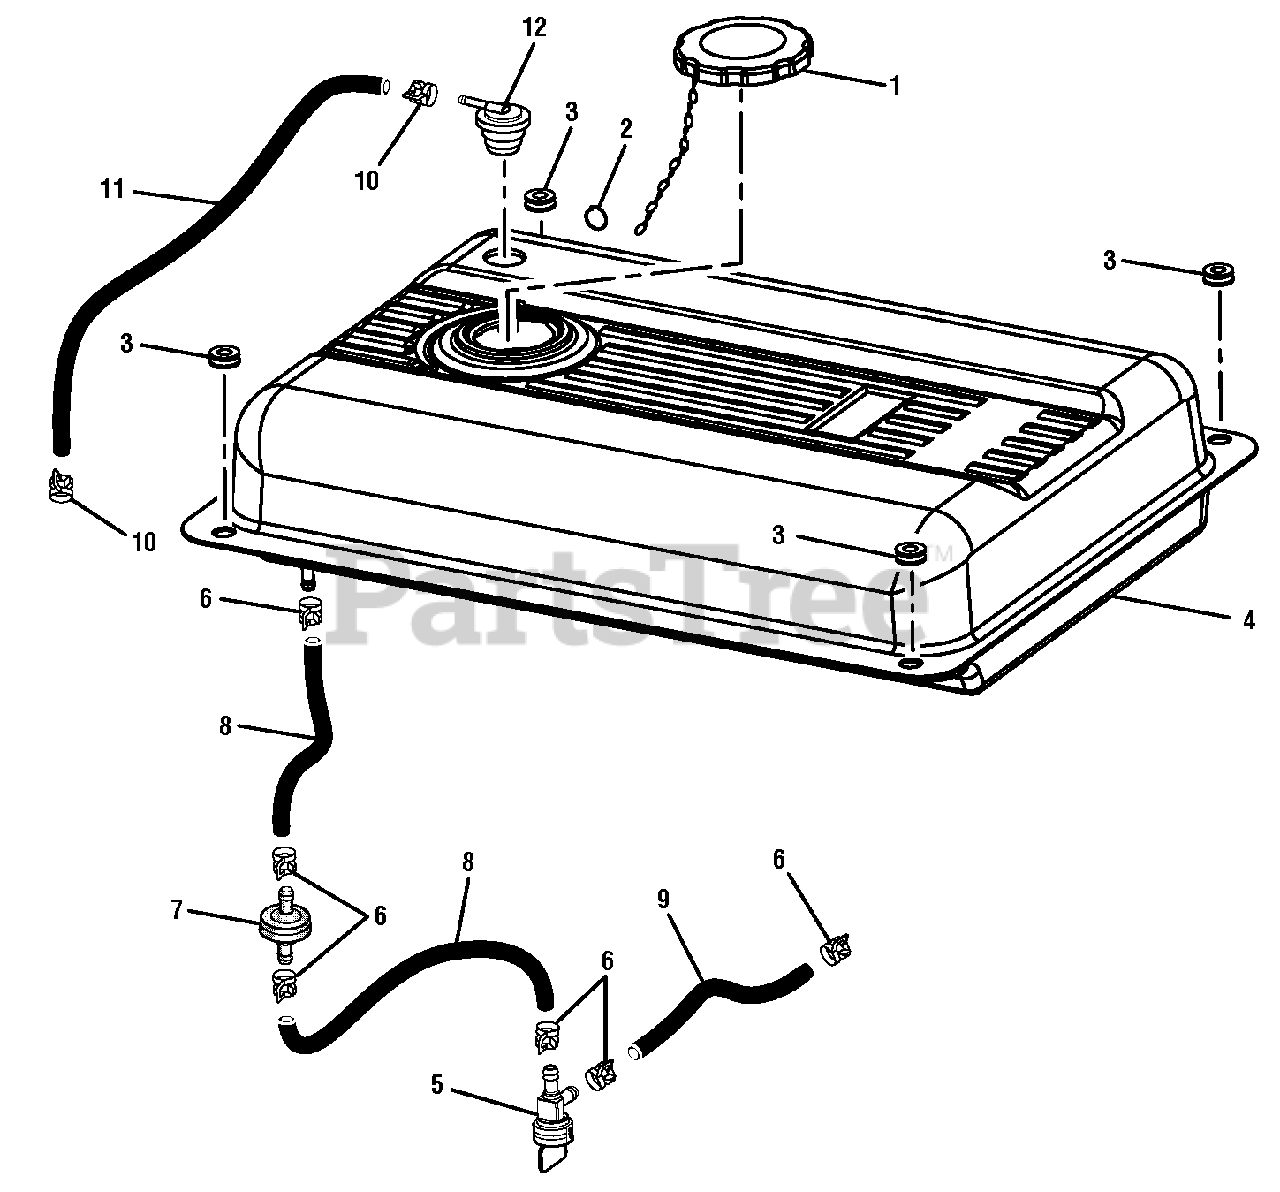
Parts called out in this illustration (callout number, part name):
1	Fuel Tank Cap
2	Ring Clip
3	Bushing w/Insert
4	Fuel Tank
5	Fuel Valve
6	Fuel Line Clamp (1/2 in.)
7	Fuel Line Filter
8	Fuel Line (1/4 in.)
9	Fuel Hose (1/4 in.)
10	Fuel Line Clamp (7/16 in.)
11	Vapor Hose
12	Vapor Vent
